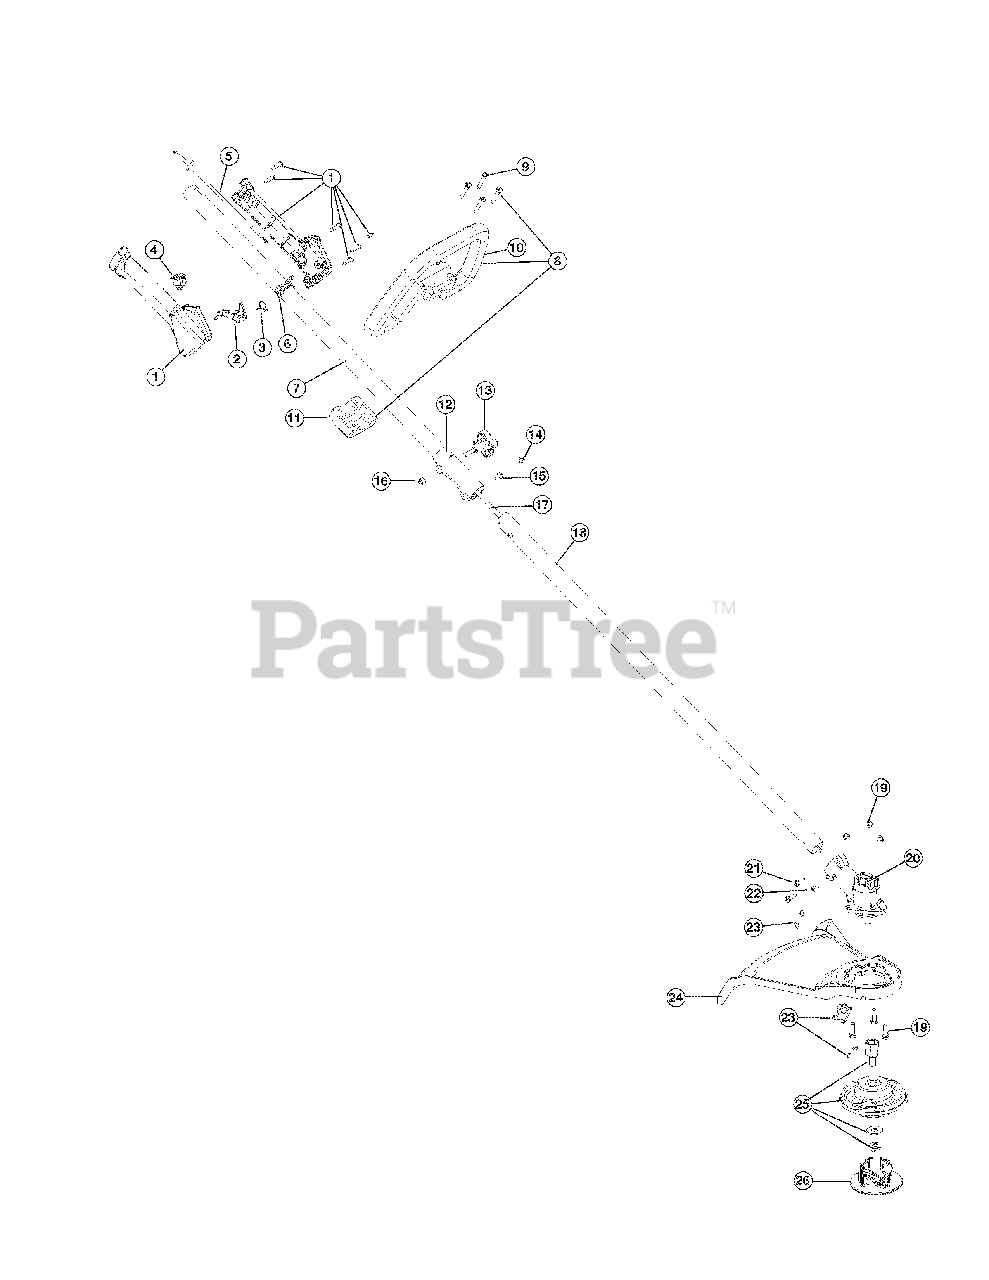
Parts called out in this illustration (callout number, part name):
1	Throttle Housing Assembly (includes 2-4)
2	Throttle Trigger
3	Throttle Trigger Spring
4	Switch Assembly
5	Throttle Cable Assembly
6	Harness Clip
7	Upper Drive Shaft Housing
8	Deluxe D-Handle Assembly (includes 9-11)
10	D-Handle
11	D-Handle Base
12	Twist Boom Coupler (includes 13-16)
13	Adjustment Knob (includes 16)
16	Nut
17	Flexible Drive Shaft
18	Lower Drive Shaft Housing
19	Shield Mount Screw Assembly
20	Gearbox Assembly
21	Gearbox Screw
22	Anti-Rotation Screw
23	Blade Assembly
24	Shield Assembly (includes 23)
25	Cutting Head Assembly
26	Cutting Head Cap
